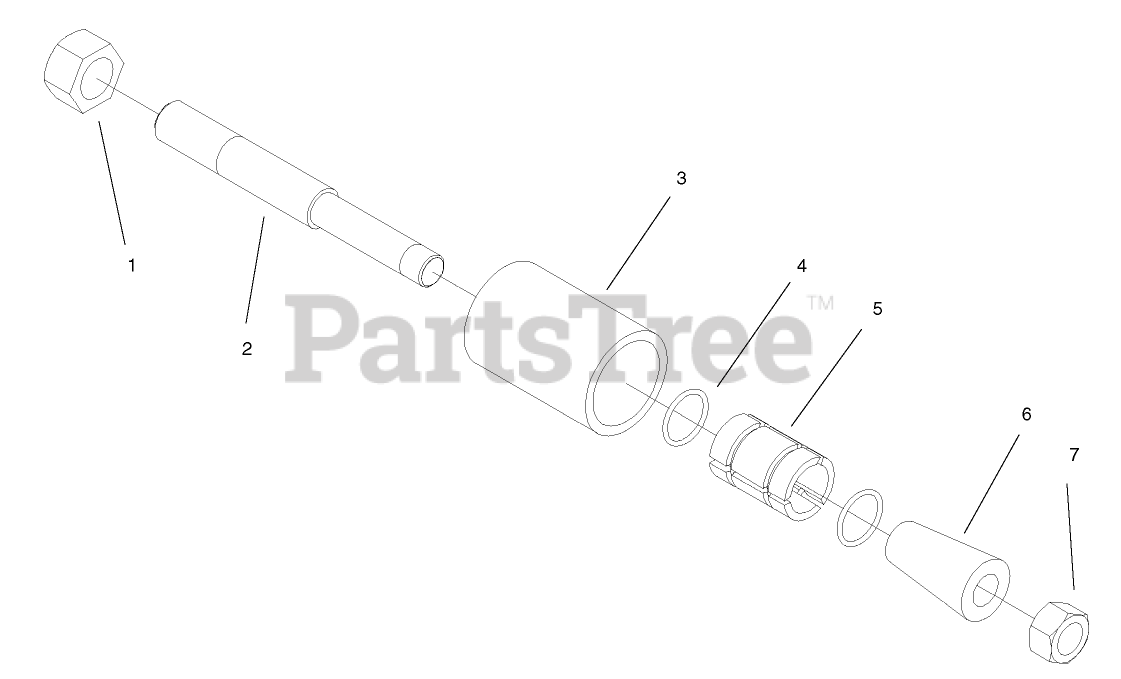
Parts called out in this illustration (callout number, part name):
1	NUT-HEX
2	ROD-PULLER
3	GRIP-OUTER
4	O-RING
5	GRIP-INNER
6	CONE-PULLER
7	NUT-HEX
